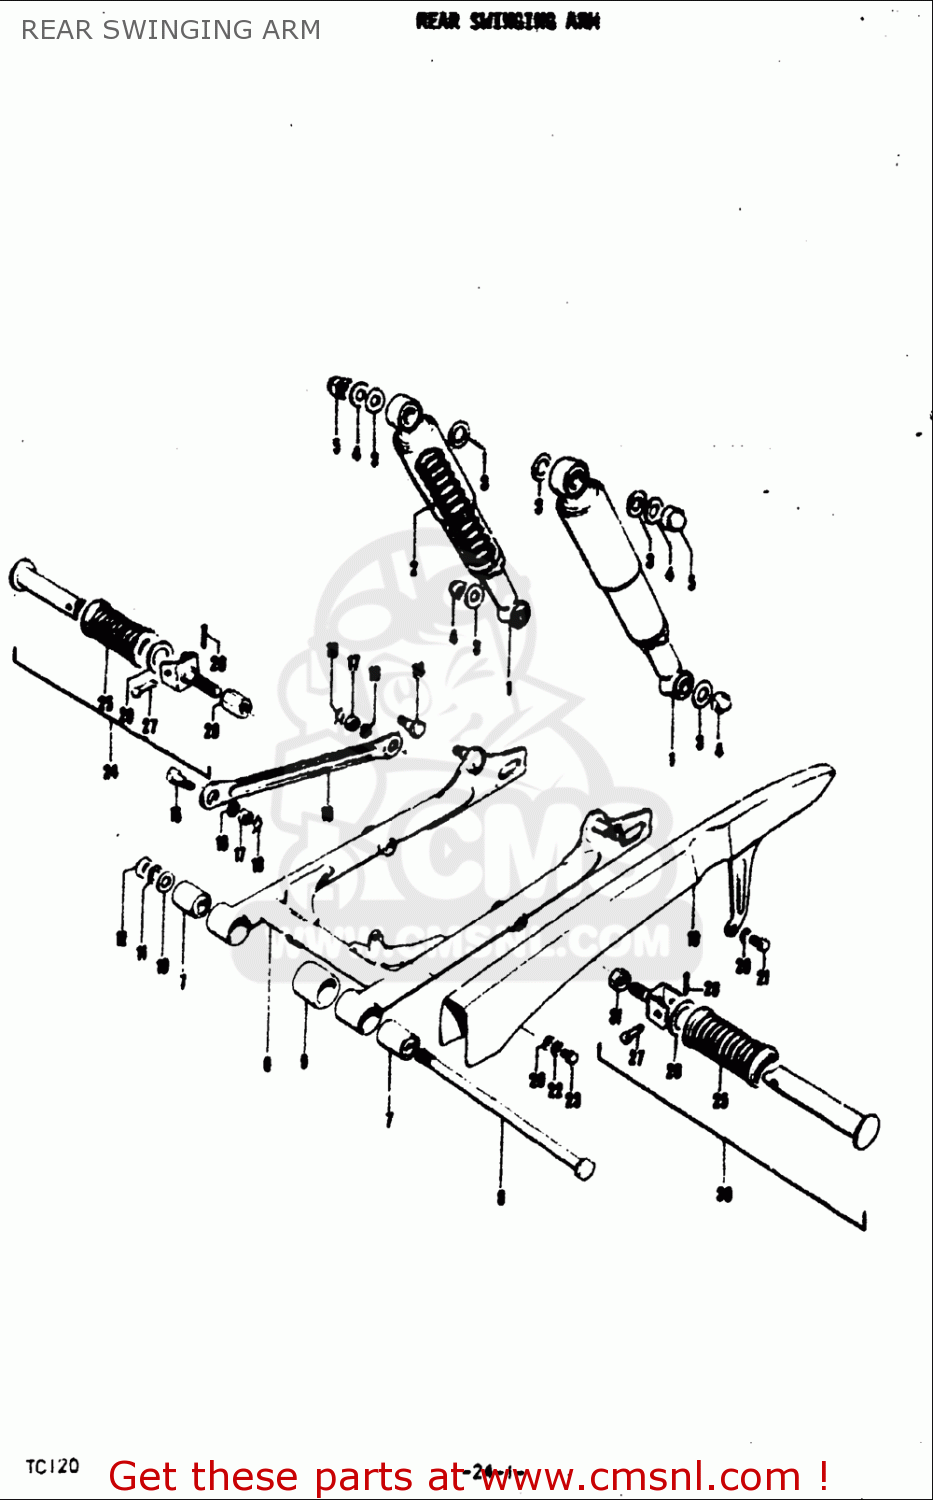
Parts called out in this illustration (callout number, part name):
3	WASHER (10.5X24X2.3)
4	WASHER
5	NUT
7	BUSHING(10X23X35)
8	SHAFT,RR SWINGINGARM PIVOT
10	WASHER
11	WASHER,LOCK
16	WASHER,LOCK
17	NUT
18	RETAINER,SNAP
20	WASHER
22	WASHER,LOCK
23	BOLT(6X14)
25	RUBBER,PILLION FOOTREST
26	WASHER(19.5X32X2)
27	PIN
29	NUT
30	FOOTREST ASSEMBLY,REAR
31	NUT
